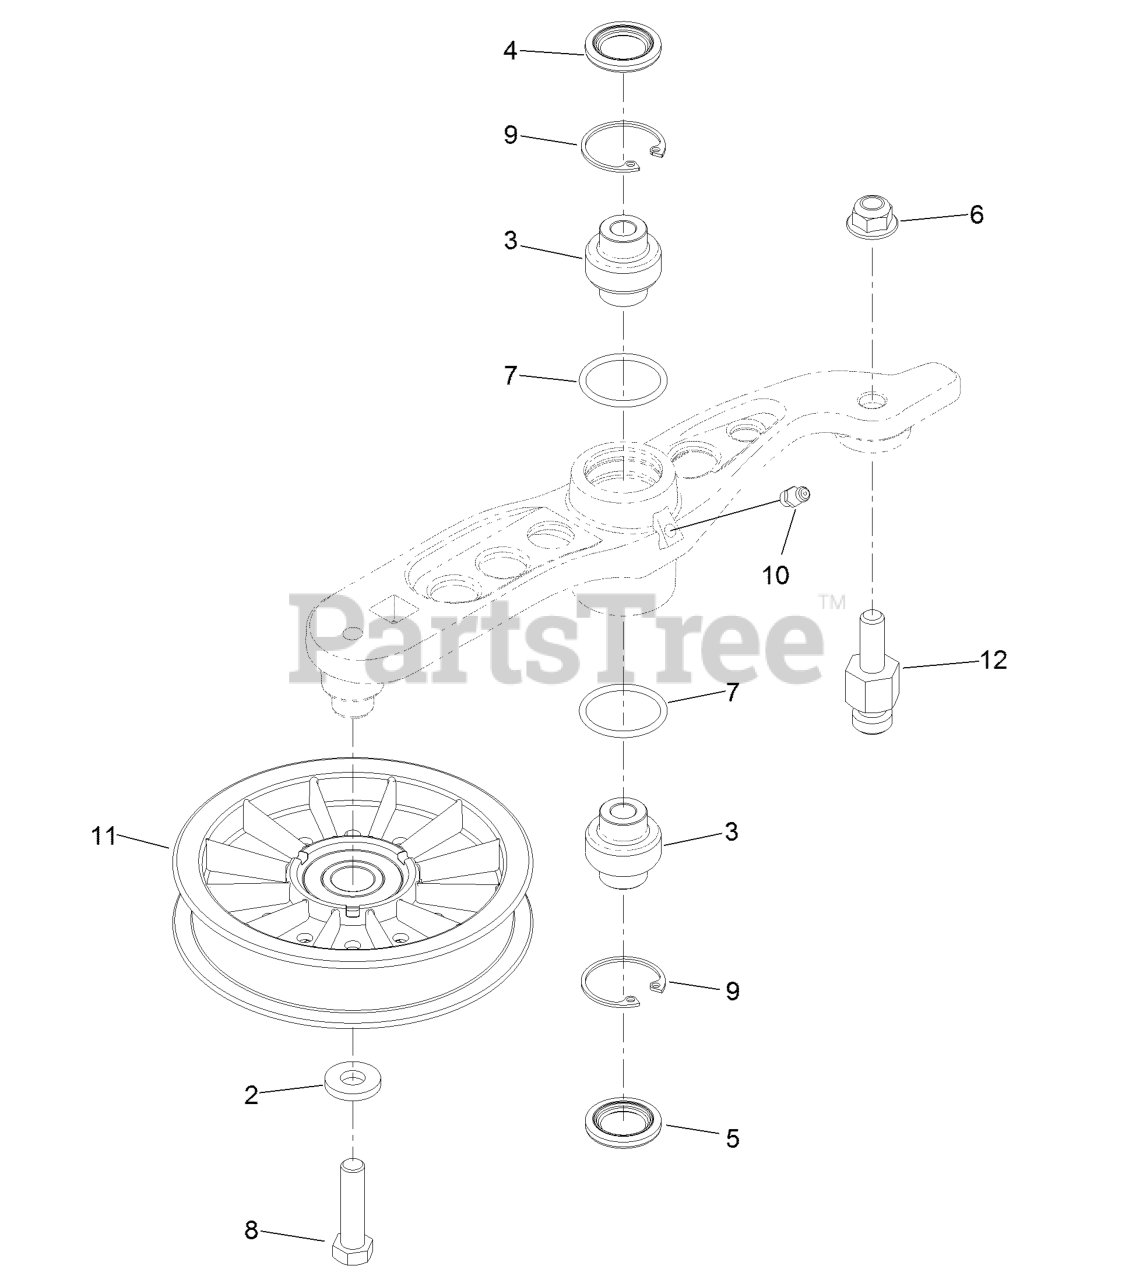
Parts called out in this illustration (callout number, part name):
3	BEARING-SPHERICAL
4	SEAL-LIP, DOUBLE
5	SEAL-LIP, SINGLE
6	Nut-Nyloc 3/8-16 Flg
8	SCREW-HH
9	RING-SNAP
10	FITTING-GREASE
11	PULLEY-IDLER
